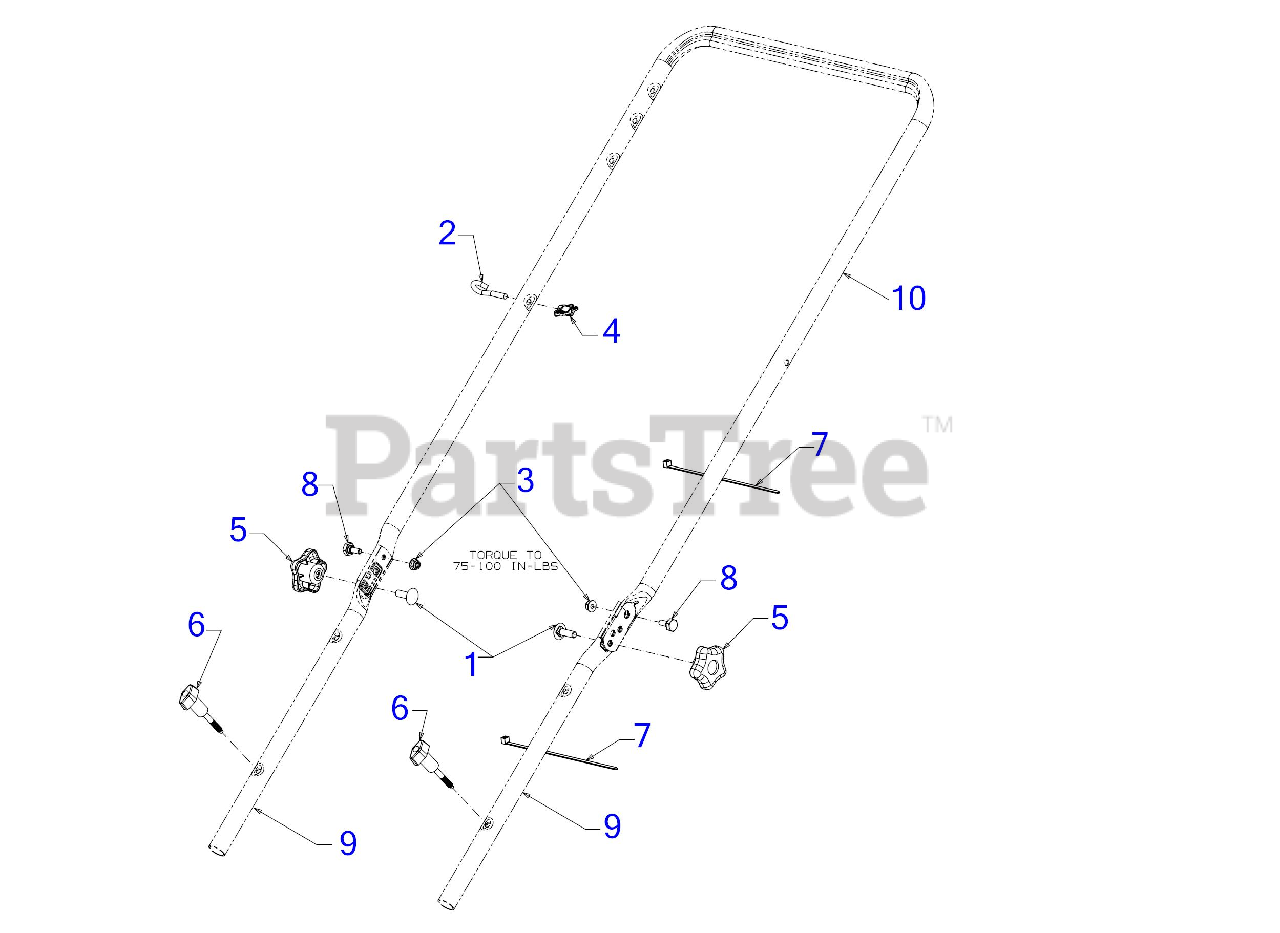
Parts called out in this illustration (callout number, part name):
1	SCREW 5/16-18 x 1.00 GR5
2	EYEBOLT 1/4-20
3	FLANGE LOCK NUT
4	HANDLE KNOB
5	STAR KNOB 5/16-18
6	WING KNOB 1/4-20
7	7" CABLE TIE
8	SHOULDER SCREW
9	LOWER HANDLE
